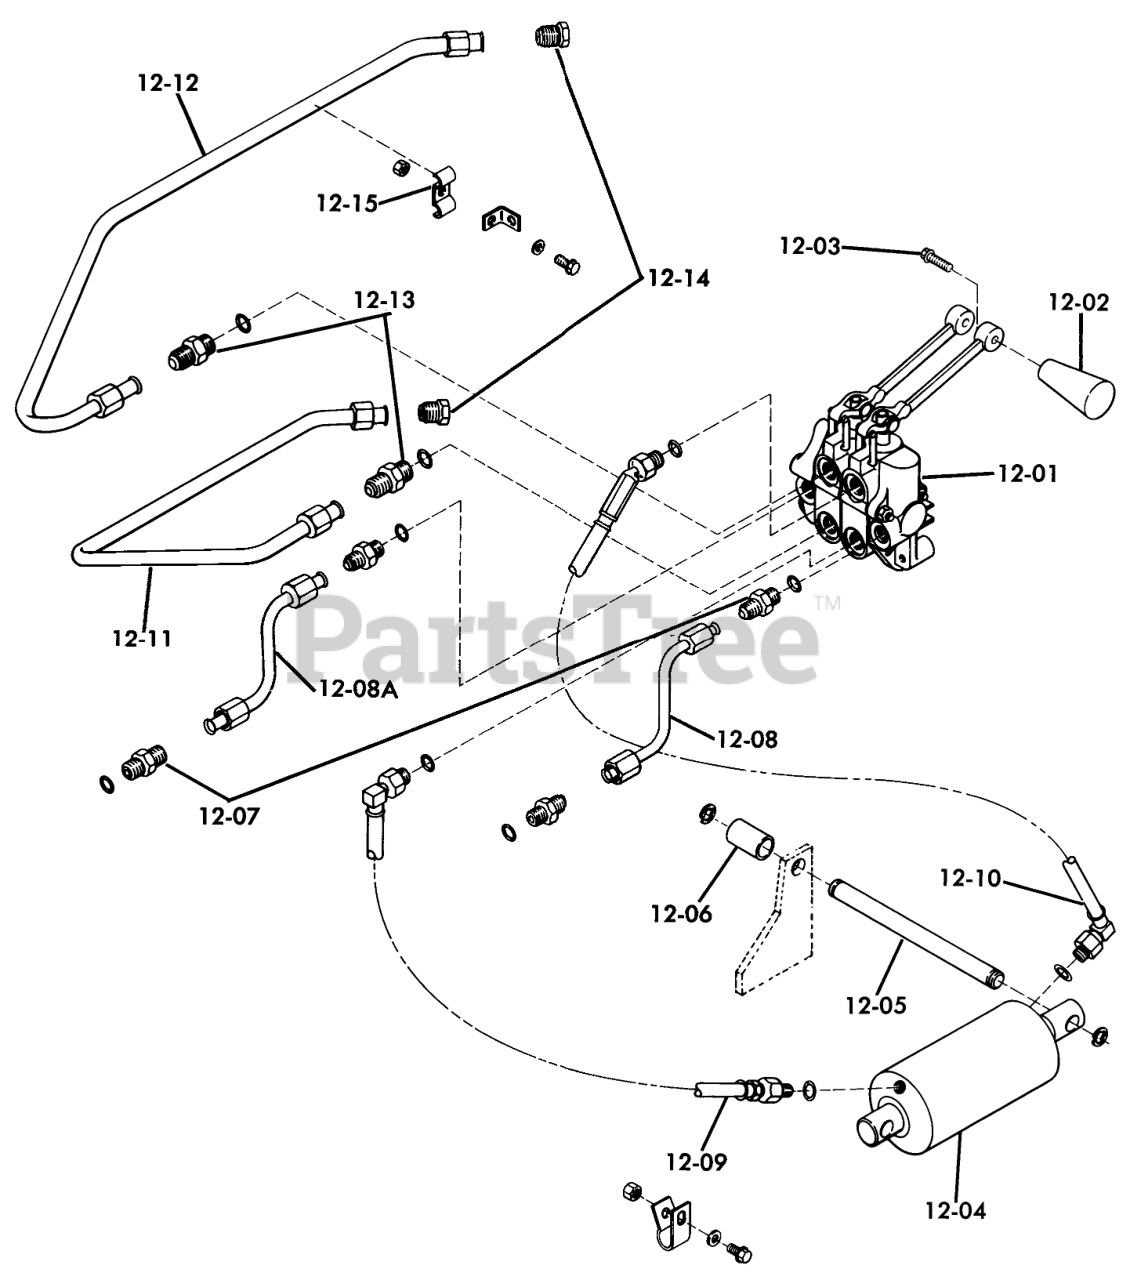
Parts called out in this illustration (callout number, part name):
12-01	Valve Assy.
12-03	SCREW
12-04	Cylinder
12-05	Cylinder Pivot
12-06	Spacer
12-07	FITTING
12-08	PRESSURE TUBE ASSY
12-08A	ASSY TUBE PRESSURE
12-09	ASSY-HYDRAULIC HOSE
12-10	Hydraulic Hose Assy
12-11	Front Tube Assy
12-12	Rear Tube Assy
12-13	FITTING
12-15	Clamp Tube
